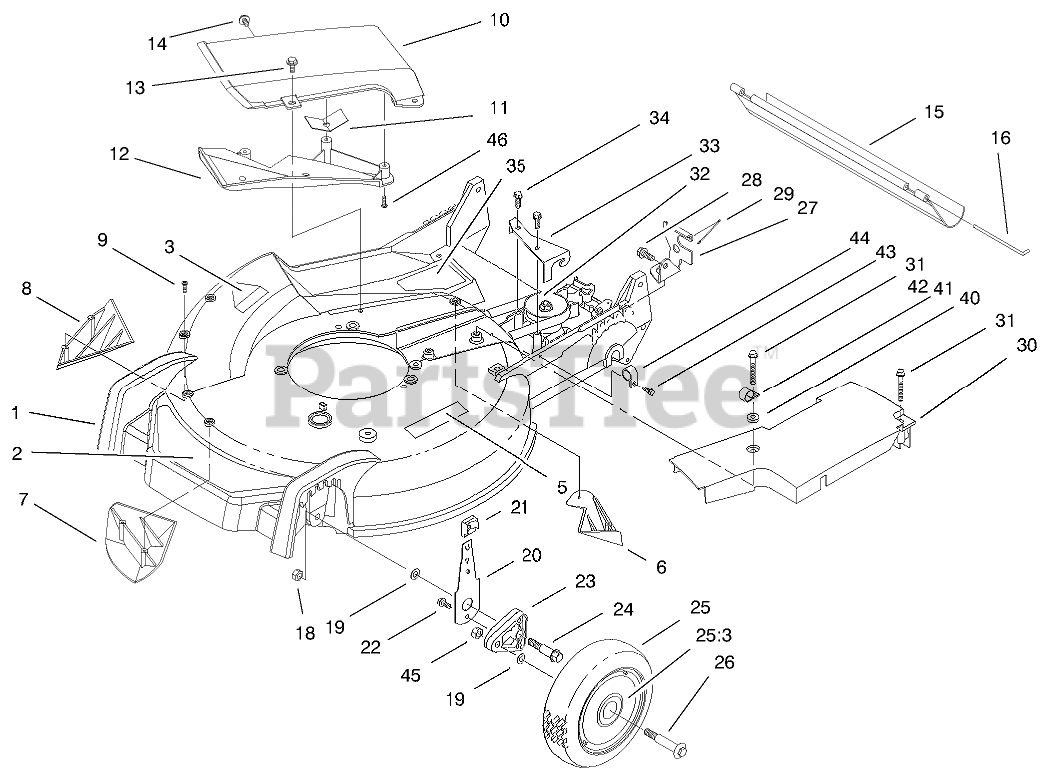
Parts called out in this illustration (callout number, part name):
1	HOUSING
2	DECAL - DECK
3	DECAL-DANGER
5	DECAL-WARNING
6	KICKER-REAR
7	KICKER-FRONT
8	KICKER-RH
9	SCREW-PPH
10	COVER W/DEFLECTOR
11	Guard-Cover
12	Deflector-Recycler
13	SCREW-HWH
14	SCREW AND WASHER ASM
15	SHIELD-TRAILING
16	ROD-SHIELD
18	NUT-LOCK
19	WASHER
20	FRONT SPRING ARM ASM
21	KNOB-ARM
22	SCREW-HWH
23	ARM-PIVOT, FRONT
24	BOLT-SHOULDER
25	WHEEL ASM
25:3	BUSHING
26	BOLT-SHOULDER
27	Bracket-Adj. Trac
28	SCREW-HWHTF
29	RETAINER-CABLE
30	COVER-BELT
31	SCREW-HHFTF
32	GEARCASE ASM
33	Bracket-Guide
34	SCREW-HWHTF
35	DECAL - DANGER
40	WASHER
41	CLAMP-CABLE
42	SCREW-SPECIAL
43	SCREW-HWH
44	CLAMP-CABLE
46	Screw-PPH
